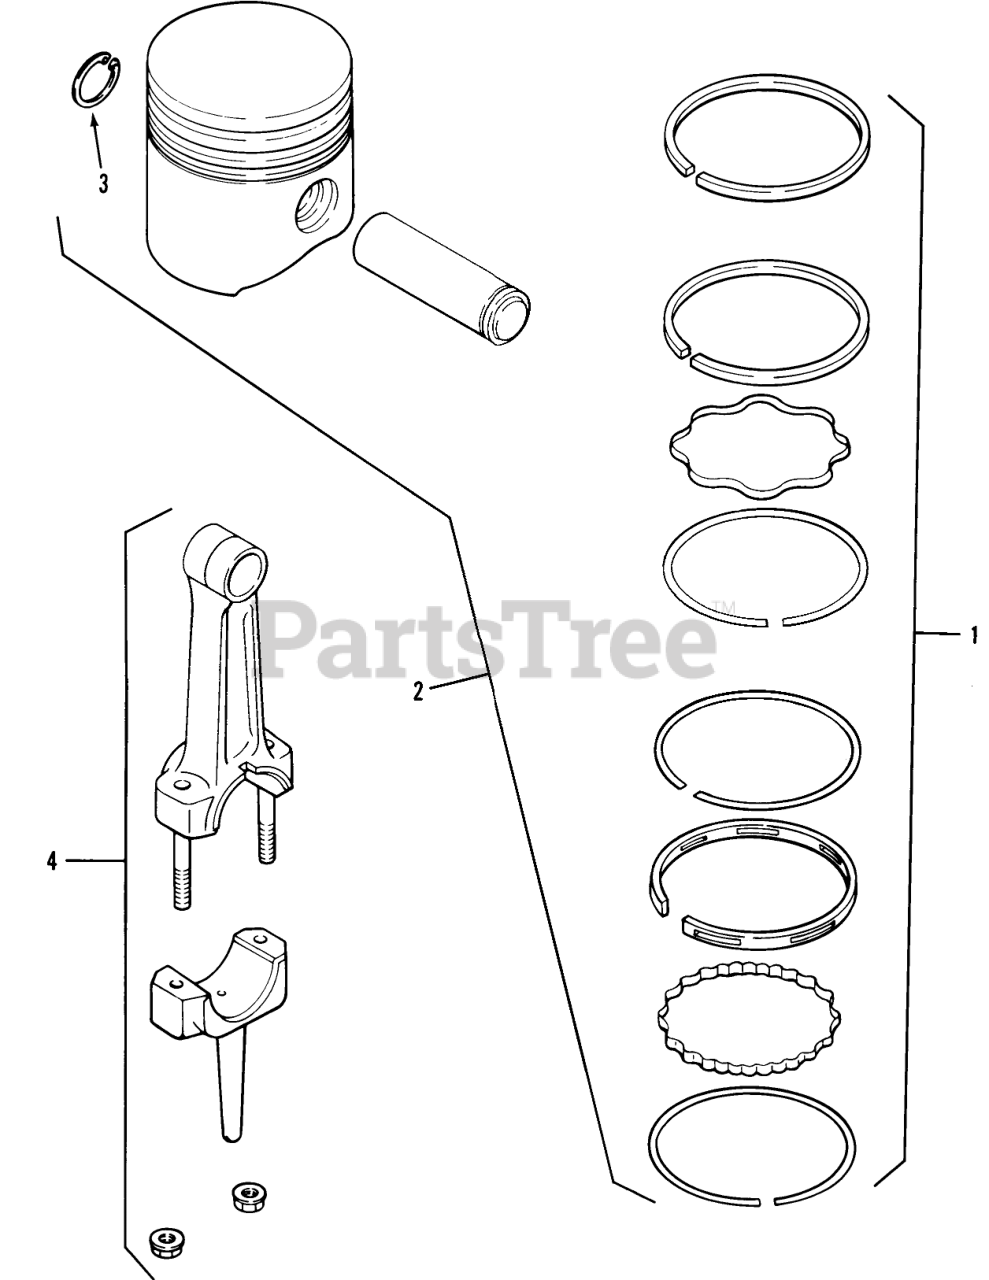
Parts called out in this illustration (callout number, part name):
1	Set-Ring, Std. & .003
1	Set-Ring .010
1	Set-Ring .020
1	Set-Ring .030
1	Ring Set Std. & .003 312
1	Ring Set .010 312
1	Ring Set .020 312
1	Ring Set .030 312
1	Ring Set Std. & .003 414
1	Ring Set .010 414
1	Ring Set .020 414
1	Ring Set .1030 414
2	Piston w/Ring Set Std
2	Piston w/Ring Set .003
2	Piston w/Ring Set .010
2	Piston w/Ring Set .020
2	Piston w/Ring Set .030
2	Piston w/Ring Set Std. 312
2	Piston w/Ring Set .003 312
2	Piston w/Ring Set .010 312
2	Piston w/Ring Set .020 312
2	Piston w/Ring Set .030 312
2	Piston w/Ring Set Std. 414
2	Piston w/Ring Set .003 414
2	Piston w/Ring Set .010 414
2	Piston w/Ring Set .020 414
2	Piston w/Ring Set .030 414
3	Piston Pin Retainer
4	Rod-Connecting Std.
4	Rod-Connecting .010
4	Connecting Rod Std. 312,414
4	Connecting Rod .010 312,414
